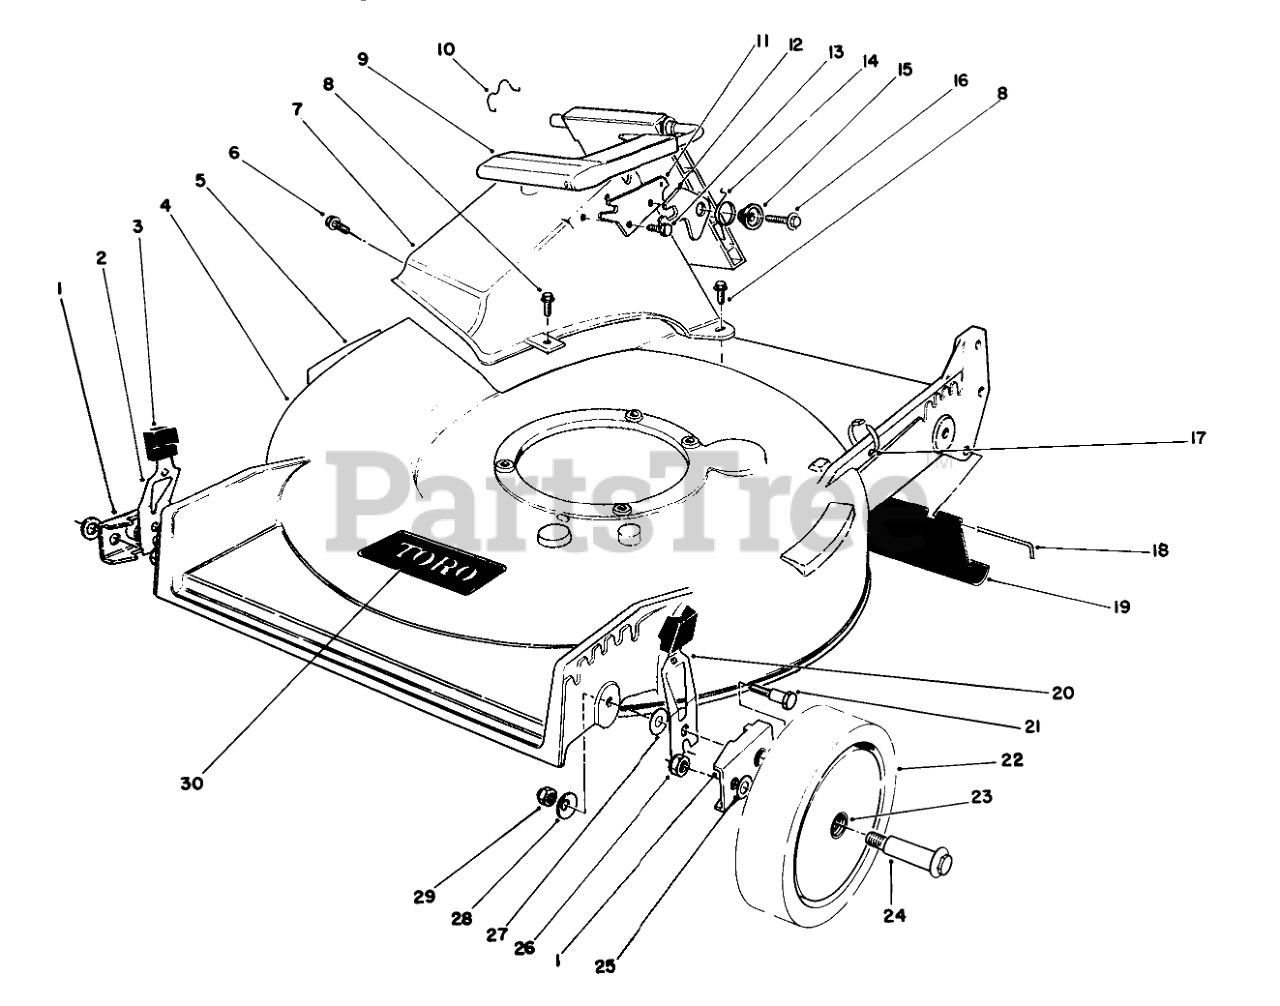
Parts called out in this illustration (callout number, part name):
1	HP PIVOT ARM ASM
2	L. HP SPRING ARM ASM
3	KNOB-ARM
4	Housing (Incl. Ref. #5)
5	DECAL-DANGER
6	SCREW AND WASHER ASM
7	Tunnel Discharge
8	SCREW-HWH
9	Discharge Door Assembly
10	DOOR RET SPRING
11	DOOR LATCH PLATE
12	SAFETY LATCH
13	SCREW-PLASTITE
14	TORSION SPRING
15	DOOR SPACER
16	SCREW-HWH
17	TIE-CABLE
18	SHIELD ROD
19	SHIELD - TRAILING
20	R HP SPRING ARM ASM
21	PIVOT SCREW
22	Wheel & Tire Assembly (Incl. Ref. #23)
23	BUSHING
24	BOLT-WHEEL
25	WASHER
26	Nut
27	WASHER-PIVOT
28	WASHER-BELLEVILLE
29	NUT-LOCK, NI
30	DECAL
